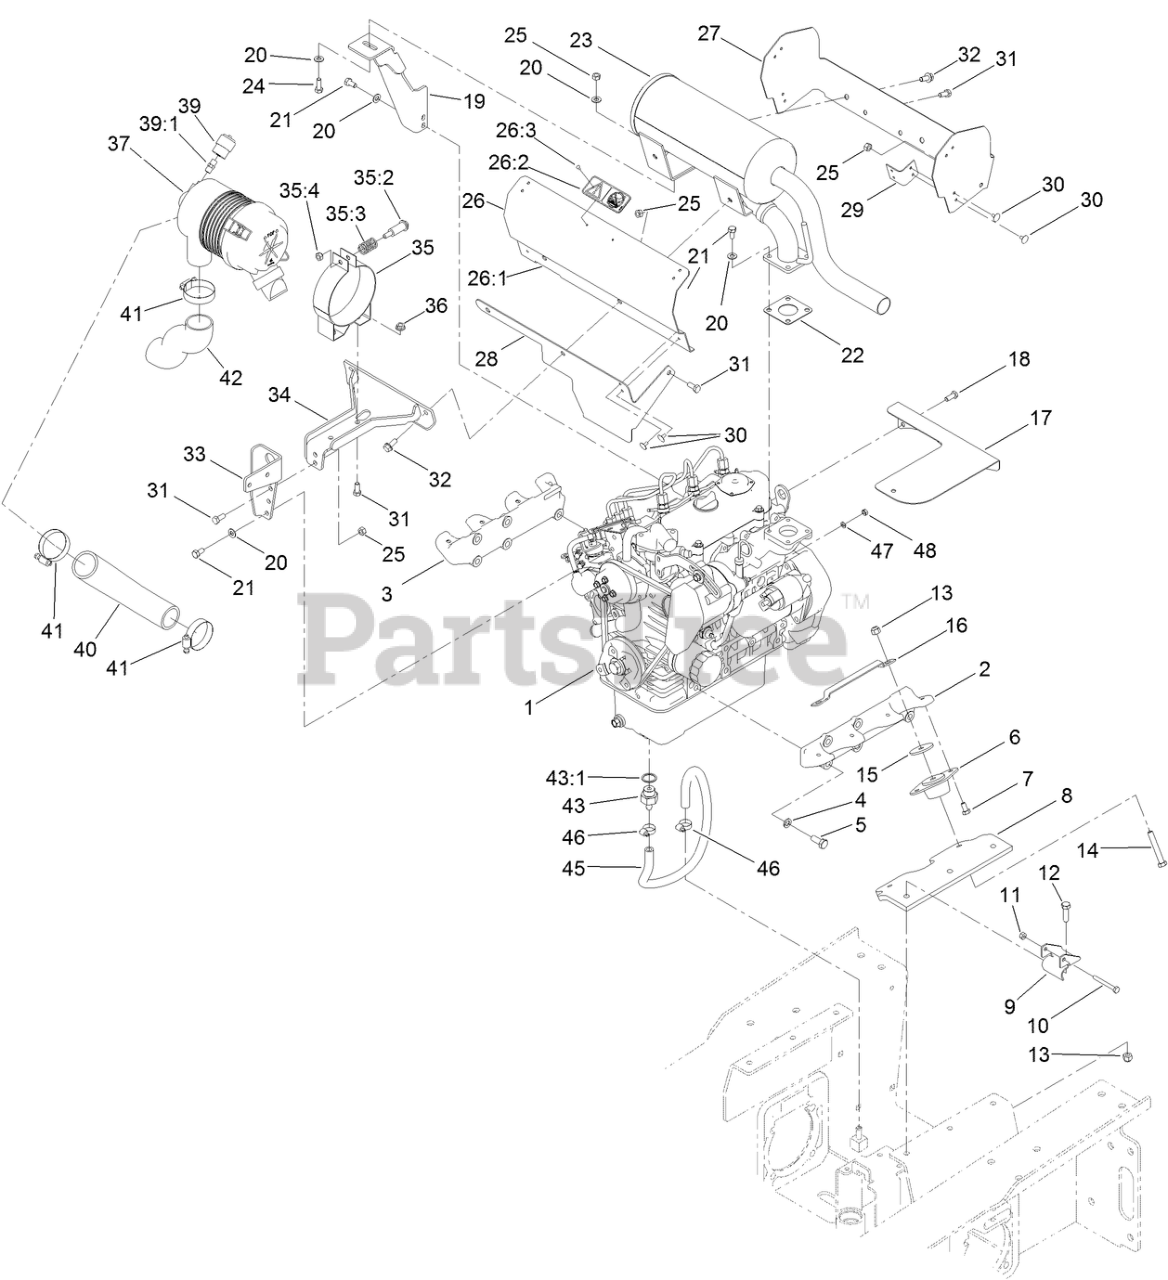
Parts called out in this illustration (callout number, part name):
1	ENGINE-KUBOTA, D902
2	MOUNT-ENGINE,LH(MACHINED)RUN W/108-6271
3	MOUNT-ENGINE,RH(MACHINED) RUN W/108-6269
4	WASHER-LOCK
5	SCREW-HH
6	MOUNT-ENGINE
7	SCREW-HH
8	PLATE-MOUNT, ENGINE
9	GUIDE-CABLE
10	SCREW-HH
11	NUT-LOCK, CONE
12	SCREW-HH
13	NUT-LOCK, NI
14	SCREW-HH
15	WASHER-REBOUND
16	STRAP-REBOUND
17	PLATE-BAFFLE, STARTER
18	SCREW-HH
19	SUPPORT-MUFFLER
20	WASHER-PLAIN
21	BOLT
22	GASKET-MUFFLER
23	MUFFLER ASM
24	SCREW-HH
25	NUT-LOCK, CONE
26	HEAT SHIELD BAFFLE ASM
26:1	PLATE-BAFFLE, MUFFLER
26:2	PLATE-HOT SURFACE
26:3	RIVET-POP
27	PLATE-BAFFLE
28	PLATE-BAFFLE, LOWER
29	BRACKET-SHIELD
30	RIVET
31	SCREW-HH
32	SCREW-HHF
33	MOUNT-FILTER, AIR
34	BRACKET ASM
35	AIR CLEANER MOUNTING BAND ASM
35:3	SPRING
35:4	NUT
36	NUT-HF
37	AIR CLEANER ASM
39	INDICATOR
39:1	ADAPTER-INDICATOR
40	HOSE-AIR, INLET
41	CLAMP-HOSE
42	HOSE-AIR
43	FITTING-HOSE
43:1	GASKET
45	HOSE-DRAIN, ENGINE OIL
46	CLAMP-HOSE
47	WASHER-LOCK, SPRING
48	NUT-HEX
